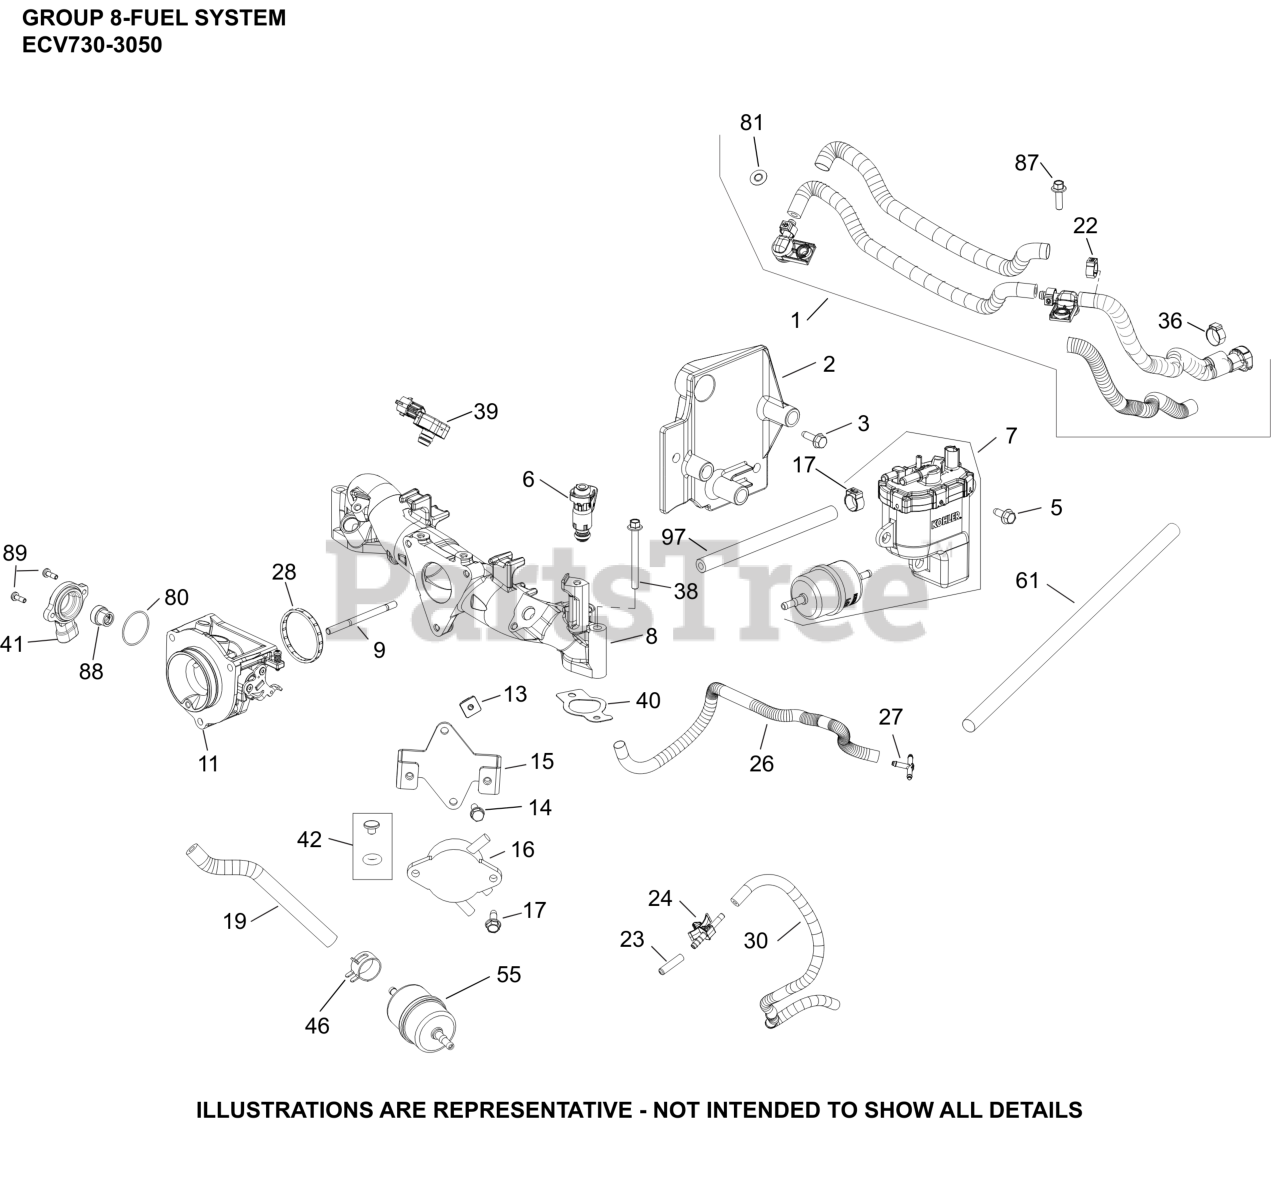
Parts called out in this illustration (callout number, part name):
1	FUEL HOSE ASSY(ECV,FCV,EZT,EKT,PCH,PCV)
2	KIT,BAFFLE, FUEL MODULE
3	SCREW, THREAD FORMING
5	SCREW, FLG M6X1.0X16
6	INJECTOR, FUEL
7	KIT, FUEL PUMP MODULE
8	KIT, MANIFOLD
9	STUD,M6X1.0X84
11	BODY, THROTTLE ASM W/ PIN (30)
13	NUT, PLASTIC - BLACK
14	SCREW, HEX HEAD
15	BRACKET, FUEL PUMP MOUNTING
16	PUMP, FUEL
17	SCREW, THREAD FORMING
19	HOSE,LW PERM.FUEL 24.00"-USE 25 111 81-S
22	CLAMP, OETIKER
23	CAP, MASKING
24	CONNECTOR, EVAPORATIVE
26	SLEEVE, ANTI-ABRASION
27	TEE CONNECTOR
28	O-RING, THROTTLE BODY
30	HOSE, EVAPORATIVE (15.0)
36	CLAMP, HOSE
38	SCREW, FLG M6X1.0X60
39	SENSOR, T-MAP
40	KIT, INTAKE MANIFOLD GASKET
41	SENSOR, THROTTLE POSITION
42	KIT, FUEL INJECTOR O-RING
46	SPRING CLAMP, HOSE
55	FILTER, FUEL
61	SLEEVE, ANTI ABRASION -USE 25 431 12-S
80	O-RING, TPS SENSOR
81	CLIP, RETAINER
87	SCREW, FLG M6x1.0x20
88	MAGNET ASSEMBLY, TPS
97	HOSE, FUEL LOW-PERMEATION
NI	SLEEVE, ANTI ABRASION-USE 25 431 12-S
